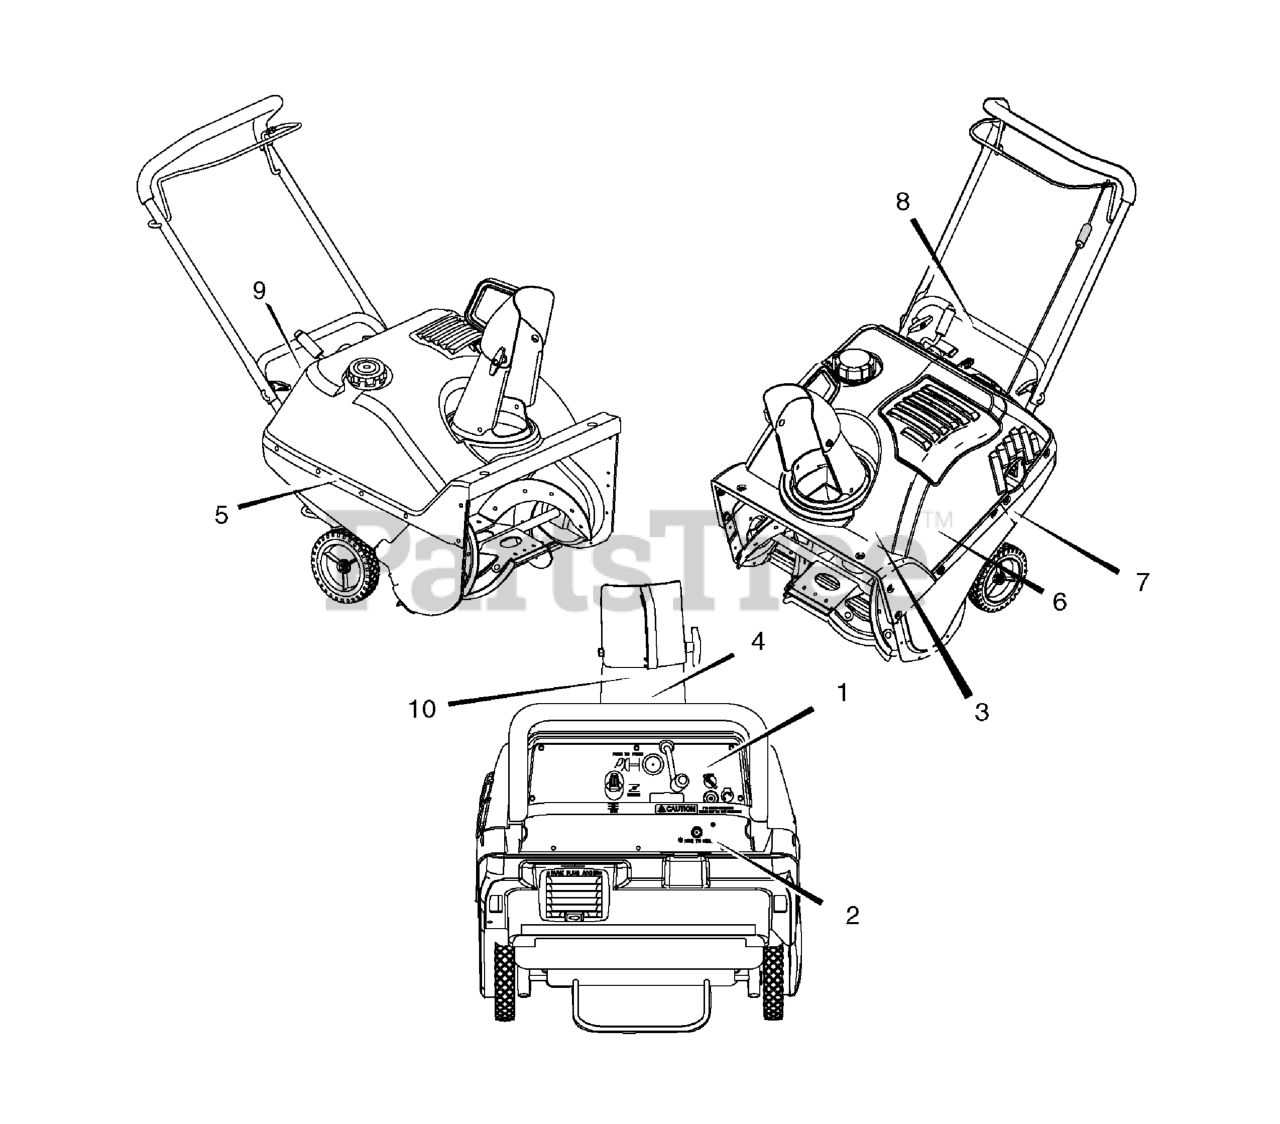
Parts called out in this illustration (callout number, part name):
1	DECAL, Control Panel Electric Start
1	DECAL, Control Panel Recoil Start
2	DECAL, Electric Start
2	DECAL, Electric Start Cover
3	DECAL, Danger Auger
4	DECAL, Danger Chute
5	DECAL, ST0522E Frontier R.H.
5	DECAL, ST0522M Frontier R.H.
6	DECAL, ST0522 Frontier L.H.
7	DECAL, Hot Muffler
8	DECAL, Auger Control
9	DECAL, Choke
10	DECAL, Thrown Objects
